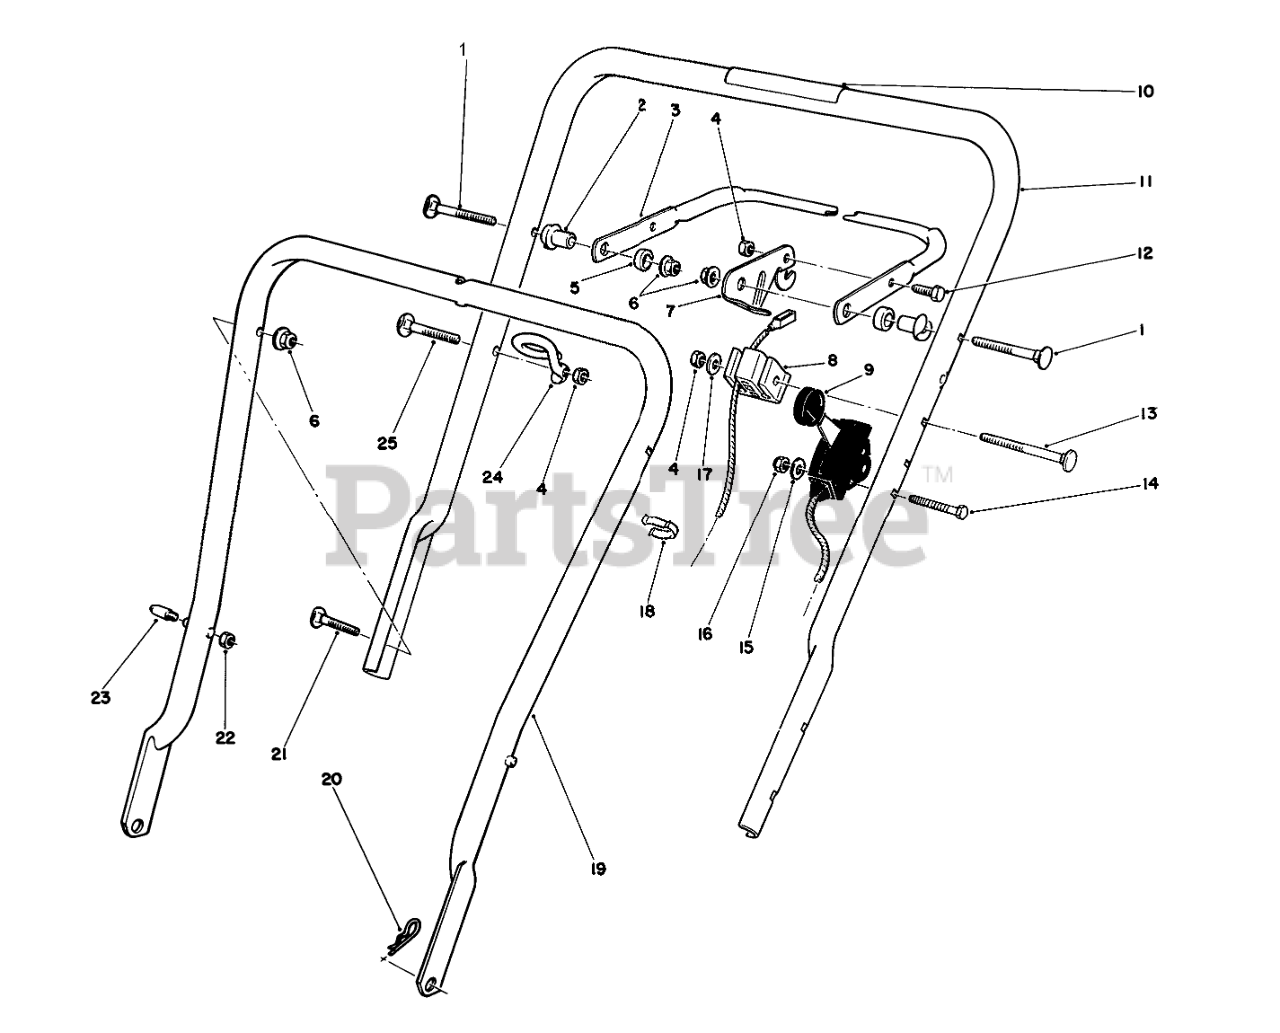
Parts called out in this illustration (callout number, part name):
1	5/16-18 X 2 HNDLE SCREW
2	SPACER-SUPPORT
3	CONTROL BAR PROMO
4	NUT-LOCK, NI
5	SPACER-NYLON
6	NUT-LOCK, NI
7	Lever-Control
8	SUPPORT-CABLE
9	Control-Throttle (Bend Type #1)(Sheath Lg. 35-1/4-)(Wire Log. 2-3/8")
10	Decal-Danger
11	UPPER HANDLE
12	SCREW-HH
13	HANDLE SCREW
14	SCREW-SHH
15	WASHER-FLAT
16	NUT-LOCK, NI
17	WASHER-FLAT
18	BOWDEN CLIP
19	LOWER HANDLE ASM
20	PIN-COTTER, HAIR
21	SCREW
22	NUT-LOCK, NI
23	HANDLE PIN
24	Guide
25	HANDLE SCREW
